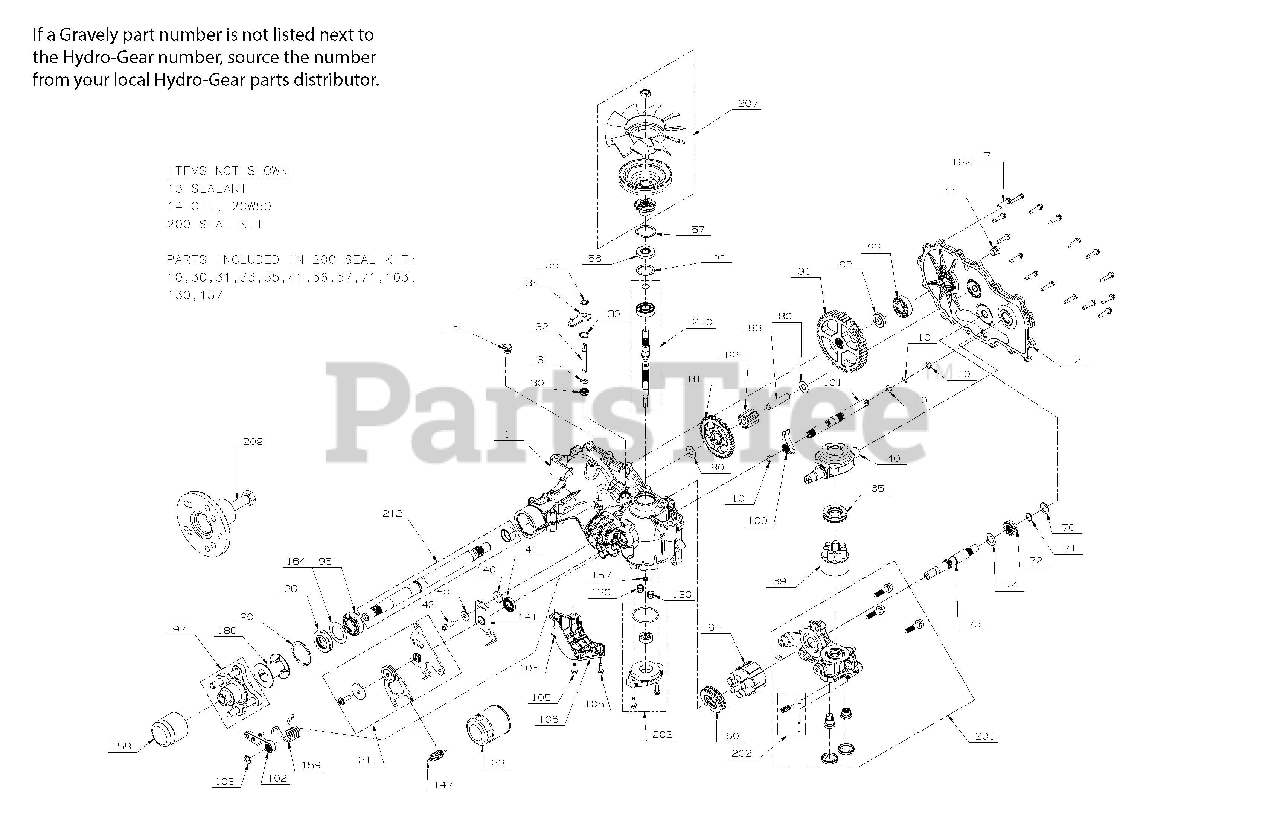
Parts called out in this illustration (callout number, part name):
1	KIT, MAIN HOUSING RH CHARGE, CONTROL
2	KIT, COVER SIDE RH
7	SCREW,HEX WASHER 1/4-20X1.125
13	SEALANT TUBE 10.1OZ.
23	OIL FILTER, TRANSMISSION
30	SEAL, LIP .375X.75X.25
31	RING. RETAINING
33	RING, RET .750
34	ARM, BYPASS
35	RING, RTNG .
40	TRUNNION, SWASHPLATE
41	SEAL, LIP 18X32X7
45	WASHER
55	WASHER 1.23X1.56X.04
56	SEAL, LIP 17X40X7
57	RING, RET 1.56 INT
60	HG THRUST BEARING (51462)
64	HG 16CC CYLINDER BLOCK (71579)
65	BEARING. THRUST 30 X 52 X 13
69	ASSY, BLOCK 7 PISTON
70	WASHER .63X1.0X.05
71	RING, RET 62 EXT
73	SHAFT, MOTOR
74	WASHER .71 X 1.16 X .04
80	WASHER .5X1.0X.032
82	GEAR, 11T (STEEL)
83	JACK SHAFT (PIN)
90	RING, RETAINING
93	KIT, BEARING
95	BEARING, BALL 25.4 X 52 X 15
96	SEAL, LIP
97	KIT, HUB 4 BOLT
100	PAWL, BRAKE
101	KIT, BRAKE SHAFT
102	KIT, BRAKE ARM RIGHT HAND
105	HFHCS 1/4-20X.75
106	GUARD, FILTER, RH
130	TUBE, CHARGE TRIPLE O-RING
140	SPACER
141	ARM, NEUTRAL RIGHT
142	SHCS 5/16-24X1 PATCH
147	RTN SPRING HG 51605
157	KIT, GEROTOR SEAL
158	CAP, AXLE
159	SPRING, TORSION CCW
164	WASHER, 1.355 x 2.035 x .021 FLAT
200	KIT, SEAL
201	KIT, CENTER SECTION RH, CHARGE
202	KIT, CHARGE RELIEF
203	KIT, CHARGE
207	KIT, FAN/PULLEY
209	HUB PULLER 4 BLT HYDGEAR 71459
210	INPUT SHAFT 2800 HYDGEAR 71442
211	RTN KIT HYDROGEAR P/N 71597
212	KIT, SHAFT, AXLE
